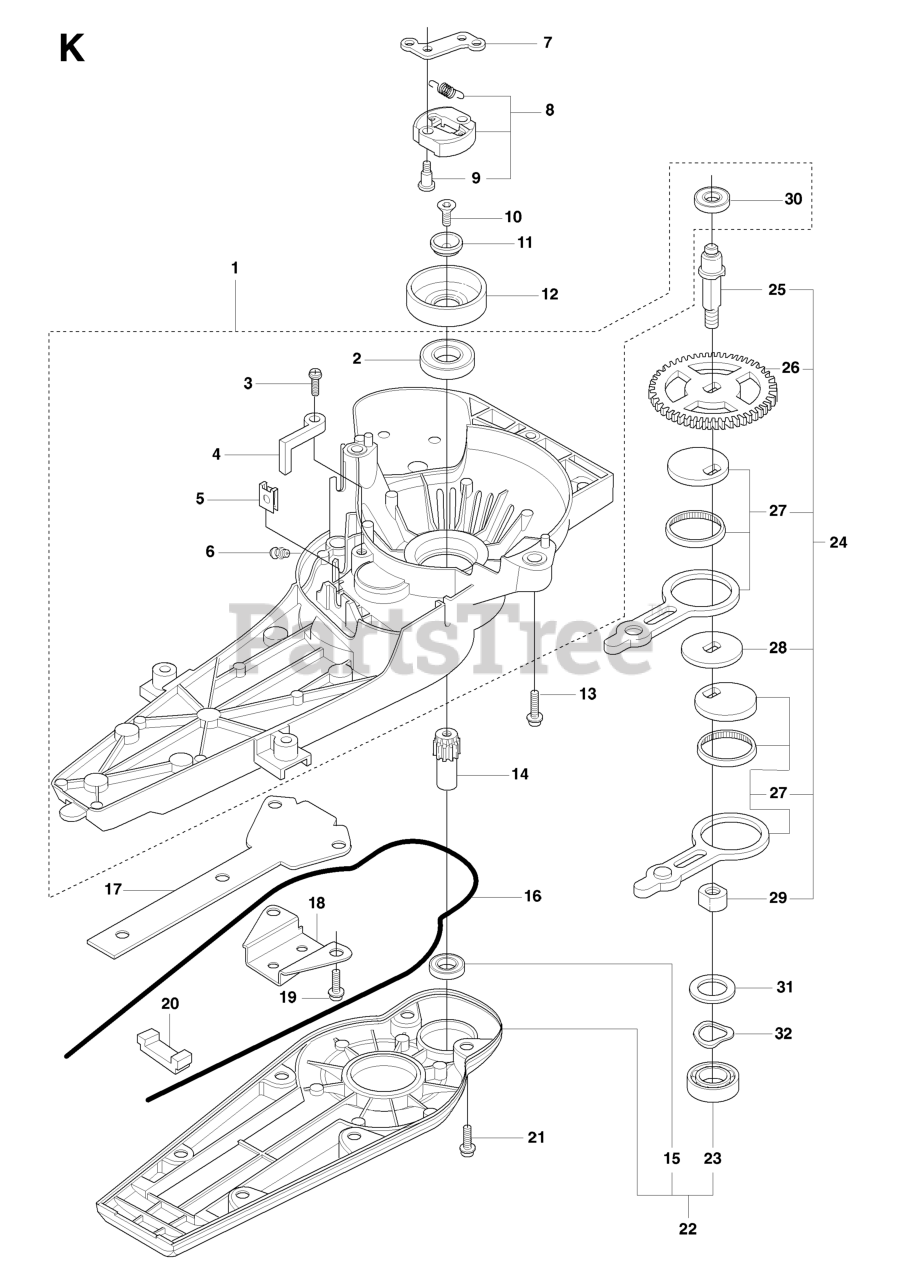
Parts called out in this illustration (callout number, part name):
1	GEAR HOUSING
2	BALL BEARING 6002-2RS1
6	GREASE NIPPLE
7	CLUTCH YOKE
8	CLUTCH CPL
12	CLUTCH DRUM
13	SCREW W/ LOCKING FLUID
27	CONNECTING ROD
30	BALL BEARING
31	WASHER 15X24
